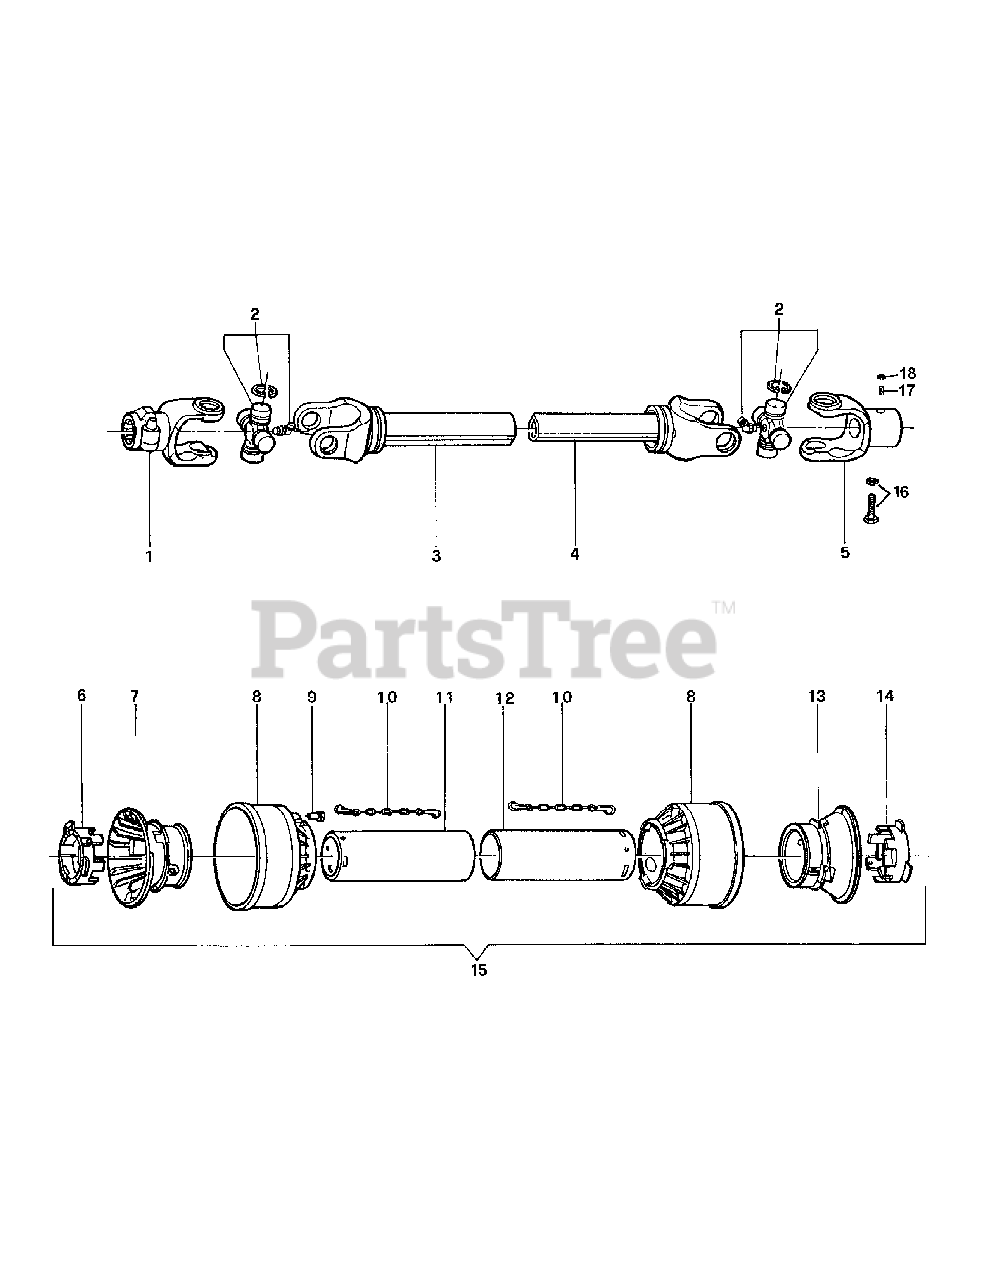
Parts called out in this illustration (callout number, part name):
1	PTO yoke (tractor end)
2	Cross and bearing
3	Outer tube with yoke
4	Inner tube with yoke
5	PTO yoke (implement end)
6	Outer locking ring
7	Outer tube rigid cone
8	Outer cone
9	Pin
10	Chain
11	Female tube shield
12	Male tube shield
13	Inner tube rigid cone
14	Inner locking ring
15	Complete shielding
16	Shear bolt and nut 3/8"x3" grade 2
17	Set screw 1/4 inch
18	Hex nut 1/4 inch
